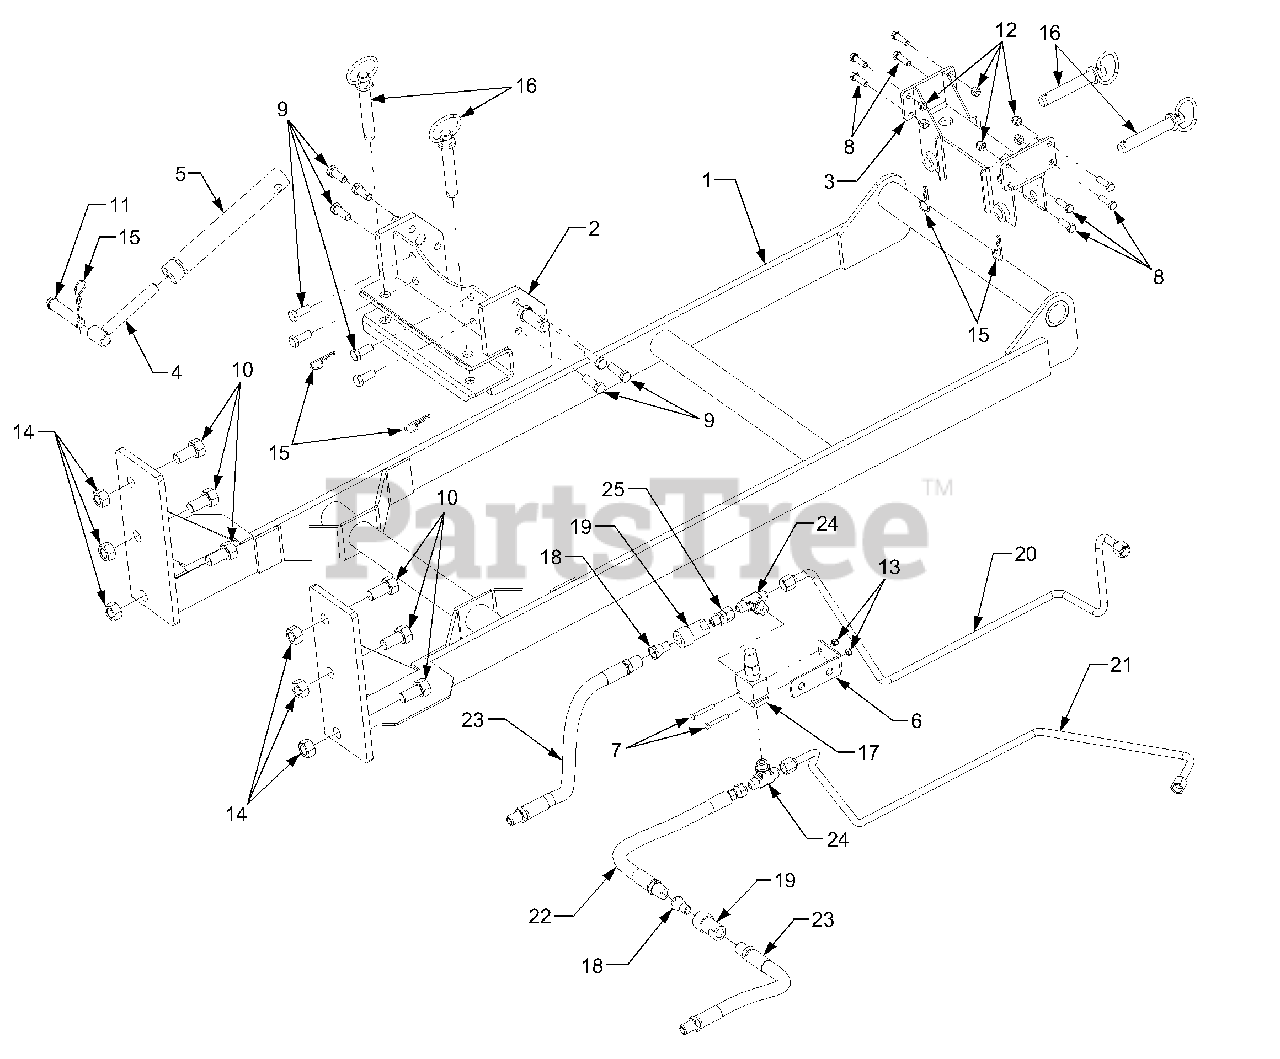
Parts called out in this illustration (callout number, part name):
2	Mounting Ass'y. Transmission
3	Latch Ass'y., Sub Frame
4	Rod Ass'y., Top Link
5	Adjuster, Top Link
6	Bracket, Valve Mounting
7	Screw, Hex Cap 1/4-20 x 1.75 GR5
8	Screw, Hex Cap 3/8-16 x 1.25
9	Screw, Hex Cap 1/2-13 x 1.25 GR5
10	Screw, Hex Cap 3/4-16 x .75 GR5
11	Pin, Clevis, .75 x 3.25
12	Nut, Hex Insert Lock, 3/8-16 GR8
13	Nut, Hex Insert Lock, 1/4-20 GR8
14	Nut, Hex, 3/4-16 GR8
15	Pin, Internal Cotter
16	Pin, Linchpin 5.50
17	Valve, Relief
18	Coupling, Hydraulic - Male
19	Coupling, Hydraulic - Female
20	Tube, Hydraulic Return
21	Tube, Hydraulic Pressure
22	Hose, Hydraulic, 1/2 ID x 18
23	Hose, Hydraulic, 1/2 ID x 29.5
24	Fitting, Orb Branch Tee
25	Fitting, Swivel Connector
